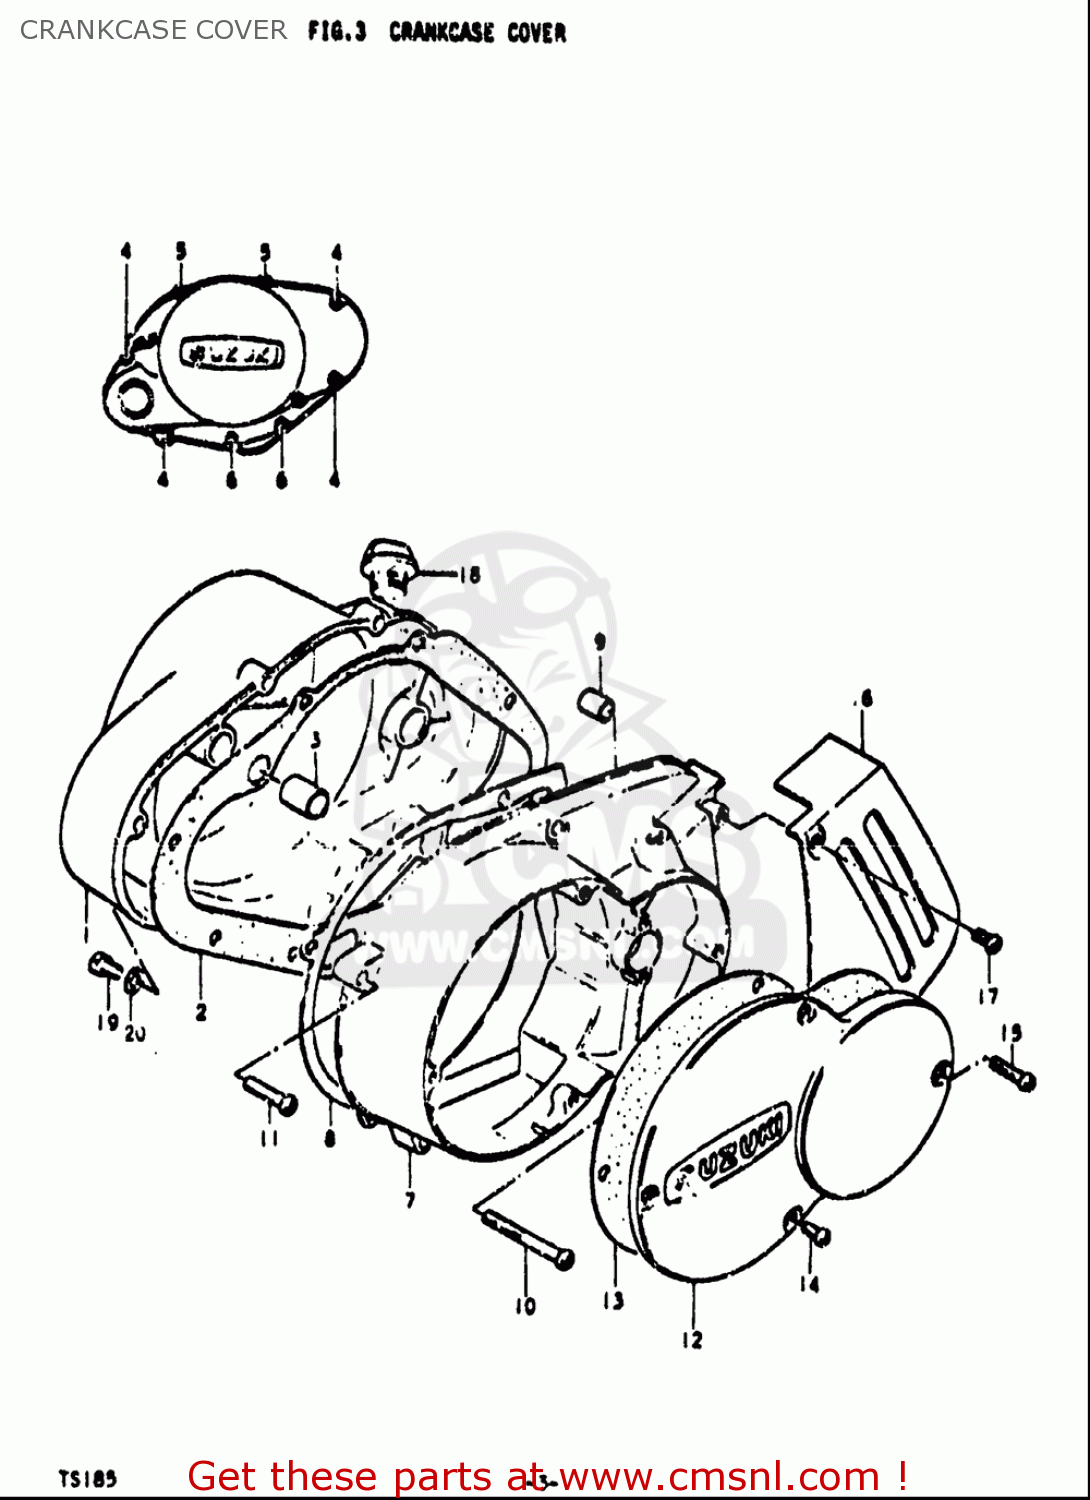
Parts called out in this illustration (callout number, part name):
2	GASKET,CLUTCH COVER
3	PIN
4	SCREW
6	SCREW
9	PIN
10	SCREW
11	SCREW
14	SCREW
15	SCREW
17	SCREW
18	PLUG SET
19	SCREW(6X10)
20	GASKET(6.2X11X1) (NAS)
